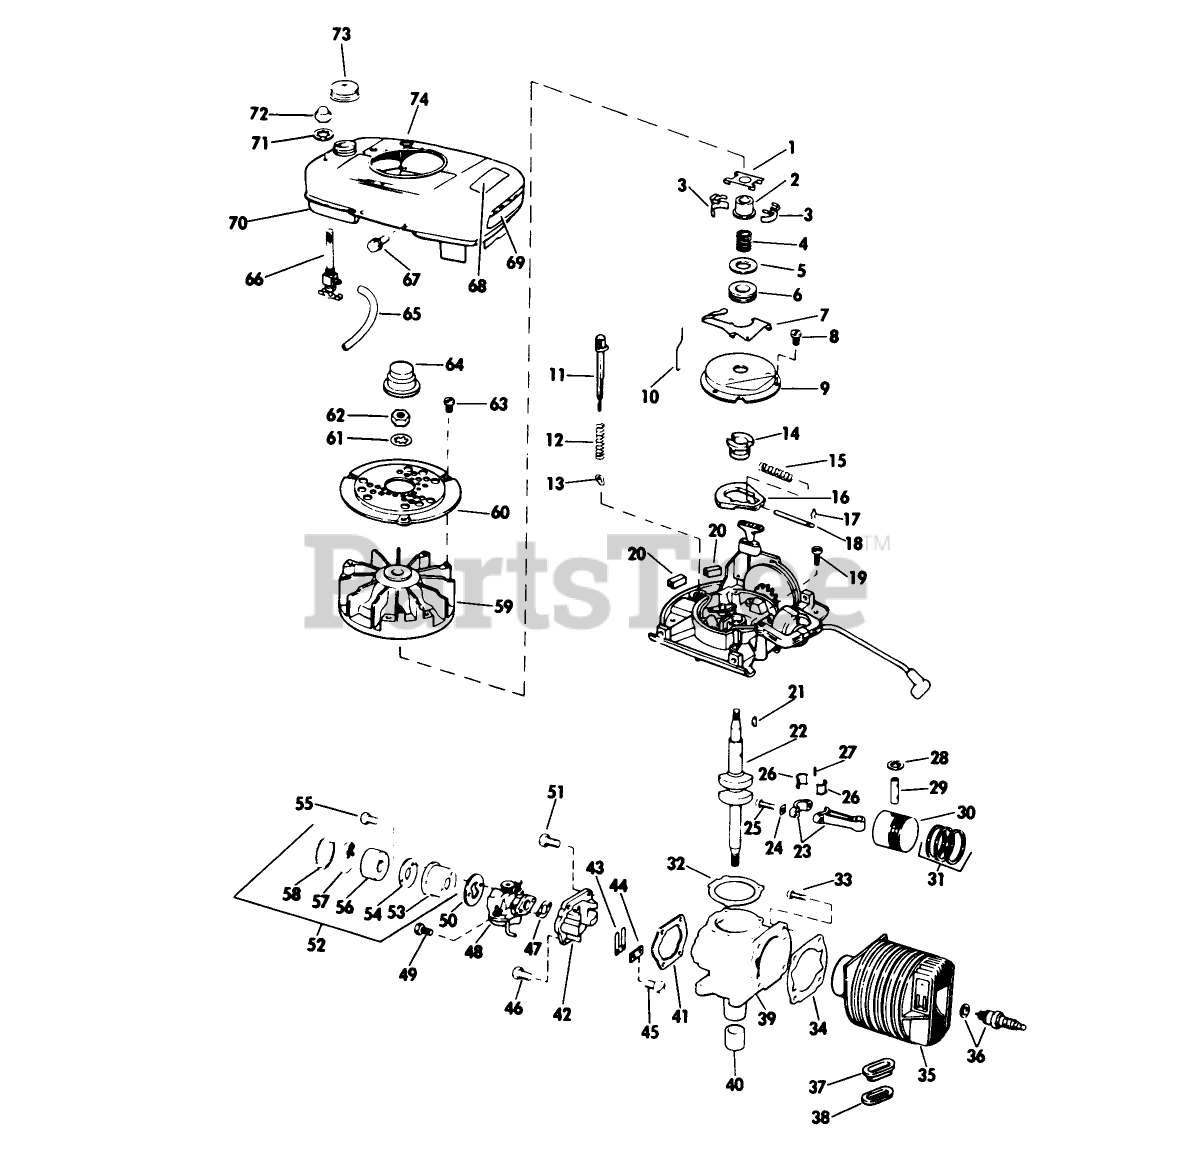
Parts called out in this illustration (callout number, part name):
2	COLLAR S
6	THRUST COLLAR S
7	LEVER-GOVERNOR S
8	SCREW S
9	DUST COVER S
12	SPRING S
14	SPARK ADV. S
15	SPARK ADV. SPRING S
16	FLYWEIGHT S
17	SPARK ADJ. SPRING
18	PIN,SPARK ADV. S
26	LINER ASM
28	RING-RETAINING
32	GASKET S
34	GASKET S
38	GASKET S
44	PLATE-BACKUP, REED
45	Screw-Machine
46	SCREW S
47	GASKET S
50	GASKET S
51	SCREW S
54	BACK-UP PLATE
55	SCREW S
56	ELEMENT
66	VALVE&SCREEN SM
67	SCREW S
72	PALNUT S
